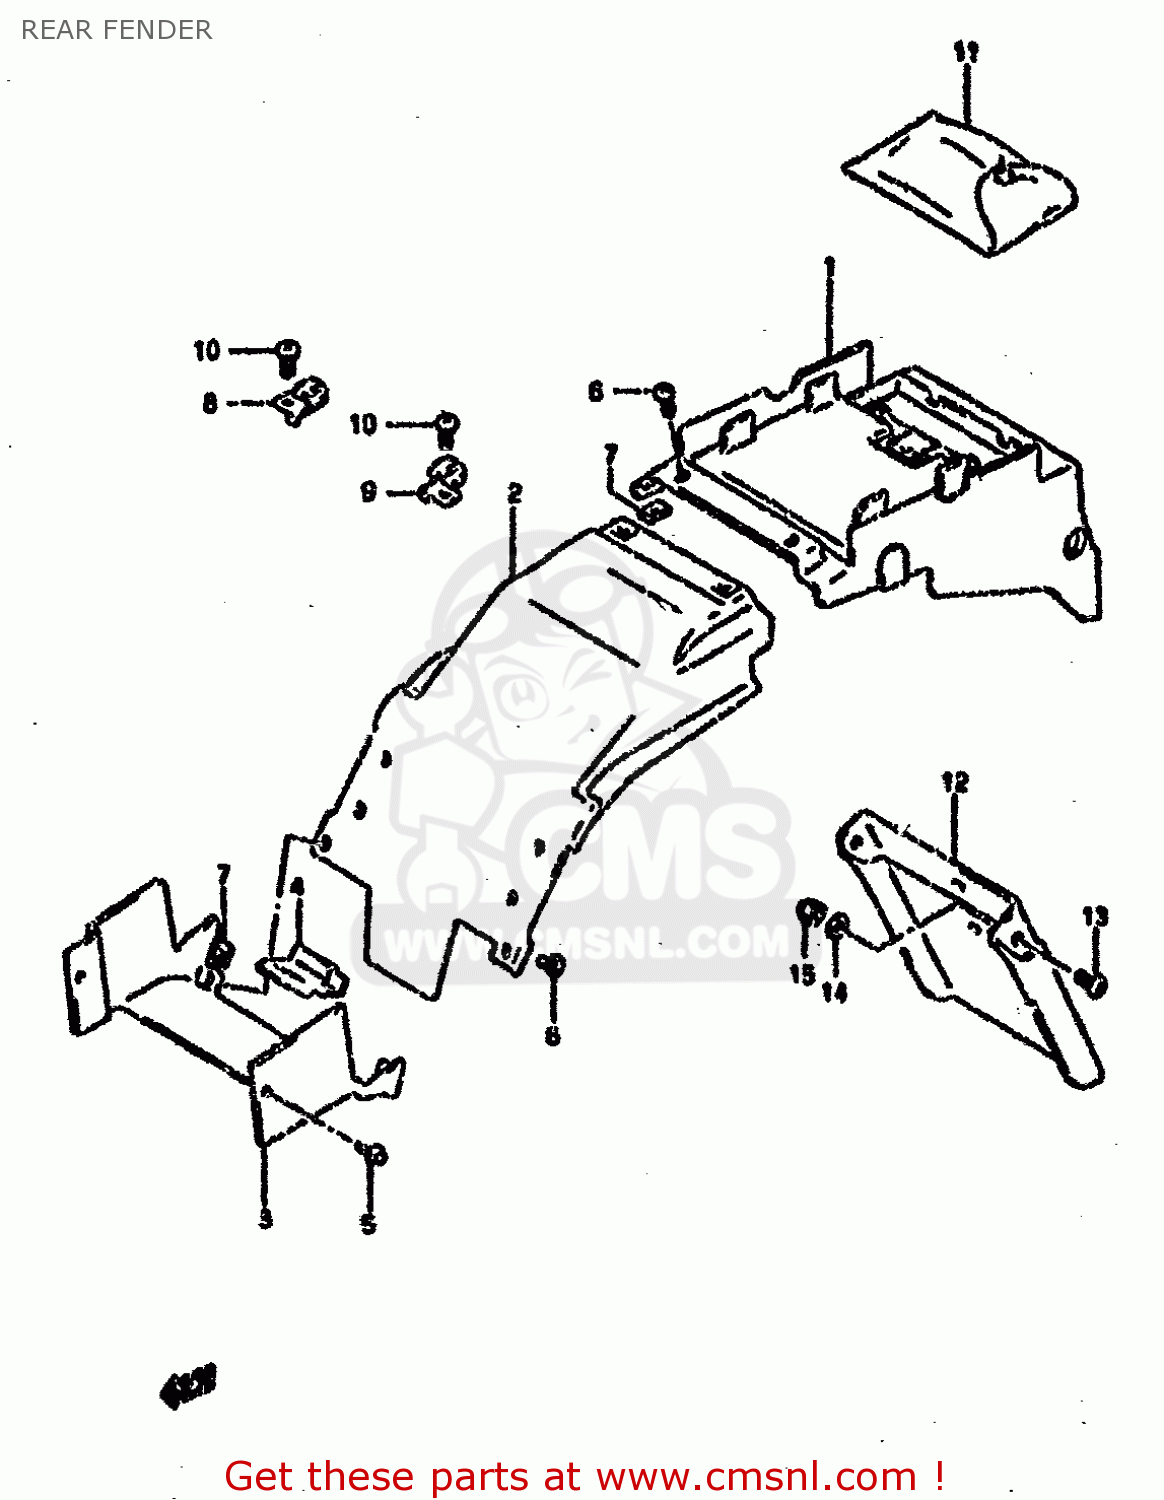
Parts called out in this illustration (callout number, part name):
1	FENDER,REAR UPPER
2	FENDER,REAR,UPPER,FRONT
3	FENDER,RR UPR FR NO.1
4	MUD GUARD,REAR FENDER
5	CLIP
6	SCREW 5X12
7	NUT,HEADLAMP HOUSING,UPPER
8	HOLDER,HELMET,R
9	HOLDER,HELMET,LEFT
10	SCREW 6X12
11	TOOL ASSY
12	EXTENSION,REAR FENDER
13	SCREW
14	WASHER
15	NUT
